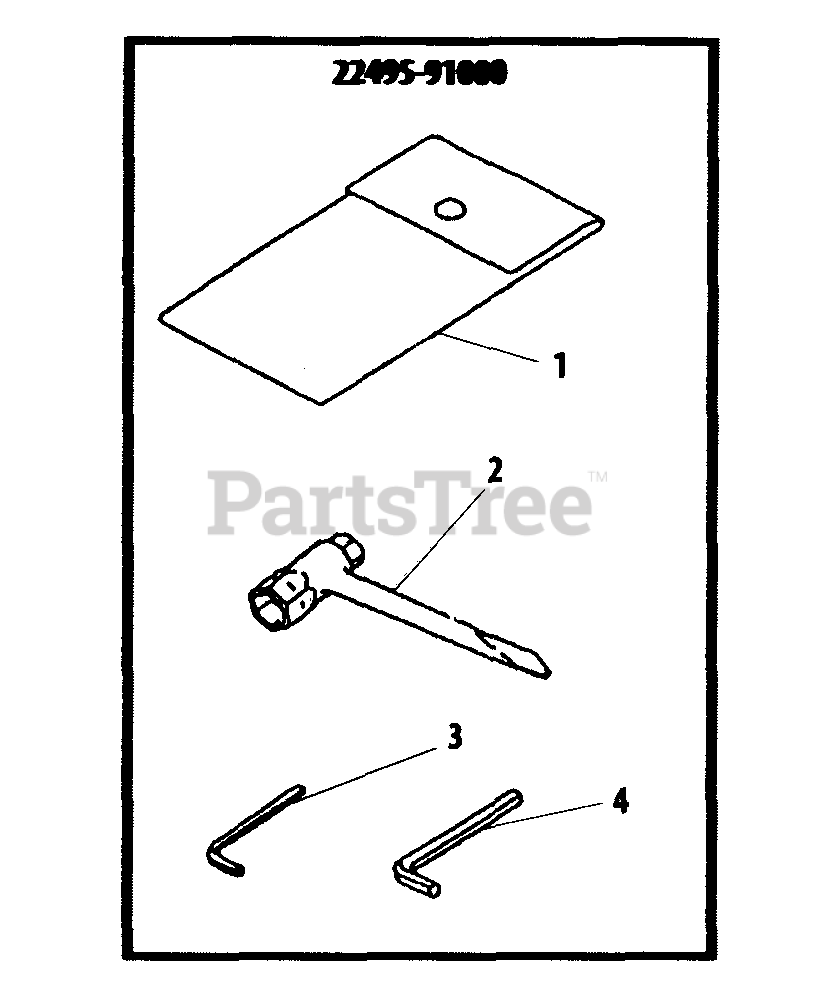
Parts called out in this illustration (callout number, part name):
1	BAG, TOOL
2	T-WRENCH 13×19 MM
3	WRENCH, ALLEN 3 MM
4	WRENCH, ALLEN 4 MM
22495-91000	SERVICE TOOL KIT
